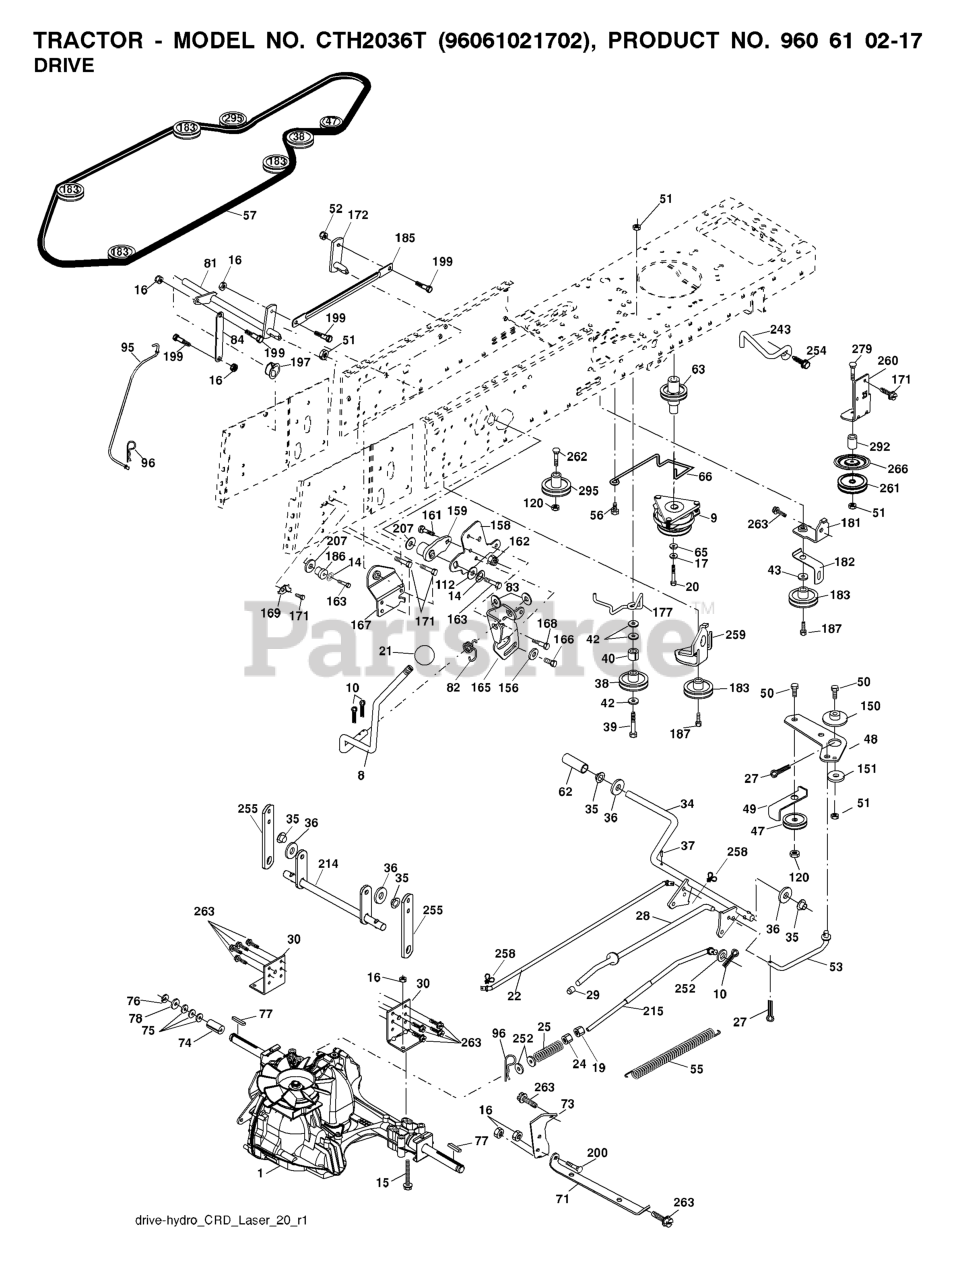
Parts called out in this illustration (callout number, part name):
8	ROD SHIFT FENDER ADJUST LT
9	CLUTCH.ELECTRIC.OGURA.EURO.
10	PIN COTTER
14	LOCKWASHER
15	BOLT HEX 5/16-18 GR 5
16	NUT.71038.31-18.HEX.NYLOCK
19	NUT
20	BOLT HEX 7/16-20X4-1/4"
21	KNOB.DUCKHEAD.1/2
22	ROD
24	NUT
25	SPRING BRAKE ROD
27	COTTER PIN
28	ROD, PARKING BRAKE
29	PLUNGER CAP
30	BRKT, TRNSXLE MNT 20"
34	SHAFT, FOOT PEDAL
35	BEARING.NYLON
37	DRIVE PIN
38	PULLEY.FLAT
42	WASHER
47	IDLER PULLEY
48	BELLCRANK, CLUTCH
49	RETAIN BELT
50	BOLT.3/8-16X1.50
52	LOCKNUT
53	LINK.CLUTCH.7.66.2005
55	SPRING, RETURN LT
56	SCREW.3/8-16
57	V-BELT 113"
62	COVER, PEDAL (1 2)
63	PULLEY.ENGINE.CVX.LT
65	LOCKWASHER
66	KEEPER BELT ENGINE
71	STRAP TORQUE LH HYDRO
73	STRAP TORQUE RH HYDRO
74	SPACER AXLE
77	SQUARE KEY
81	ASM.CROSS.SHAFT.REAR.CRD.0510
82	SHIFT SPRING
83	WASHER
84	LINK.PNT.TRANSAXLE.0510.CRD
95	LINK
96	RETAINER M
120	NUT LOCK FLG 3/8-16 UNC
150	BUSHING.BELLCRANK.GRD.DR
151	WASHER 12/32X2X10GA
156	WASHER.SRRTD.5/16
158	BRACKET
159	RB HUB.SHIFT
161	BOLT
162	NUT.CROWNLOCK.1/4
165	RP BRACKET
166	CAPSCREW.HXHD.FLG.5/16-18X.625
167	BRACKET.SUPT.SHIFT.CRD
168	BOLT.SHOULDER.5/16-18X
169	PLATE.FASTENING.CROSS.SHAFT
172	LINK
181	BRACKET
182	BELT GUIDE
183	PULLEY.V-IDLER.GRND.DR
185	LINK
186	HUB.TAPERED.ROUND.CRD
187	BOLT.5/16-18X1.25
197	NYLINER SNAP 5/8" ID
199	BOLT SHOULDER 5/16-18 UNC
207	WASHER NYL
214	LEVER
215	ROD
243	BRACKET, ANTI-ROTATION
252	WASHER
254	SCREW 3/8-16X1
255	SHAFT
258	CLIP RETAINER
259	BRACKET
261	FLAT IDLER PULLEY
263	SCREW, 3/8-16X3/4
266	PROTECTOR
292	SPACER
295	PULLEY IDLER COMPOSITE
